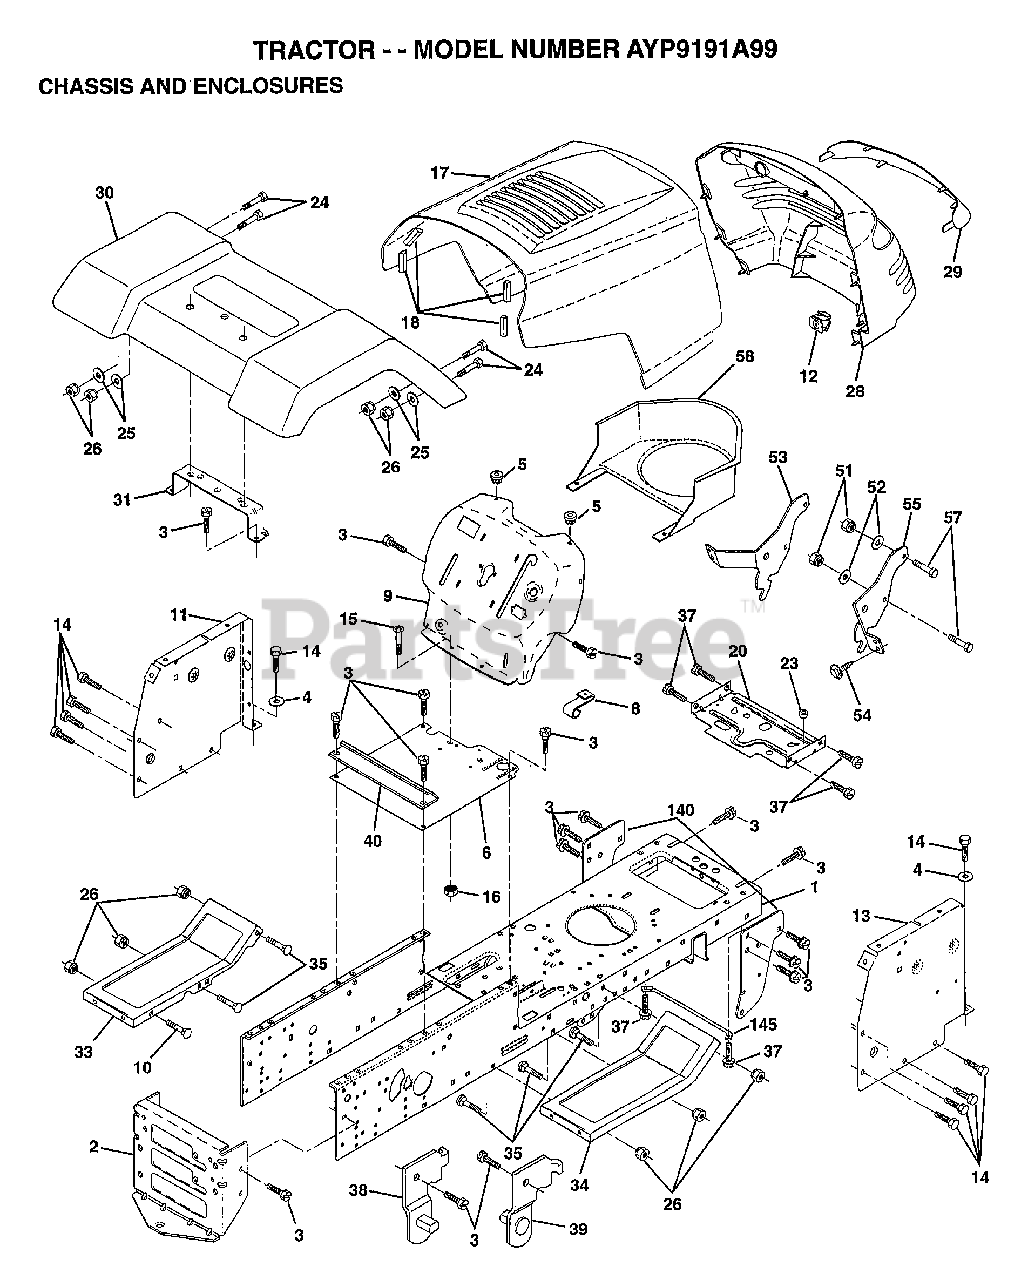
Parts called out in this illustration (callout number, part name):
1	CHASSIS.STAMPING
3	SCREW
4	WASHER
5	BUMPER-HOOD/DASH
6	SADDLE
8	CLIP RETAINER SLIDE-ON
9	DASH SILKSCREEN
11	"PANEL-DASH,LH"
12	CLIP.TINNERMAN
14	SCREW LT
15	SCREW
17	HOOD.STEEL.ASSY
20	"PLATE-MTG,BATT/FU"
24	BOLT
25	WASHER
26	NUT
28	GRILLE-MS428
29	LENS.GRILLE.PRIVATE LABEL
30	FENDER.PNT.ASSY
31	BRACKET SUPT FEND
33	FOOTREST.LH.LT/GT
34	FOOTREST.RH.LT/GT
35	BOLT
37	SCREW LT
38	BRACKET ASM LH
39	BRACKET ASM RH
40	SPACER FENDER LT
51	NUT
52	WASHER
53	BRACKET.GRILLE.LH
54	SCREW.HEX.WS.HD
55	BRACKET.GRILLE.RH
58	DUCT.AIR.B&S.18HP
140	BRKT SUSPENSION
145	"ROD POVOT,CHASSIS"
